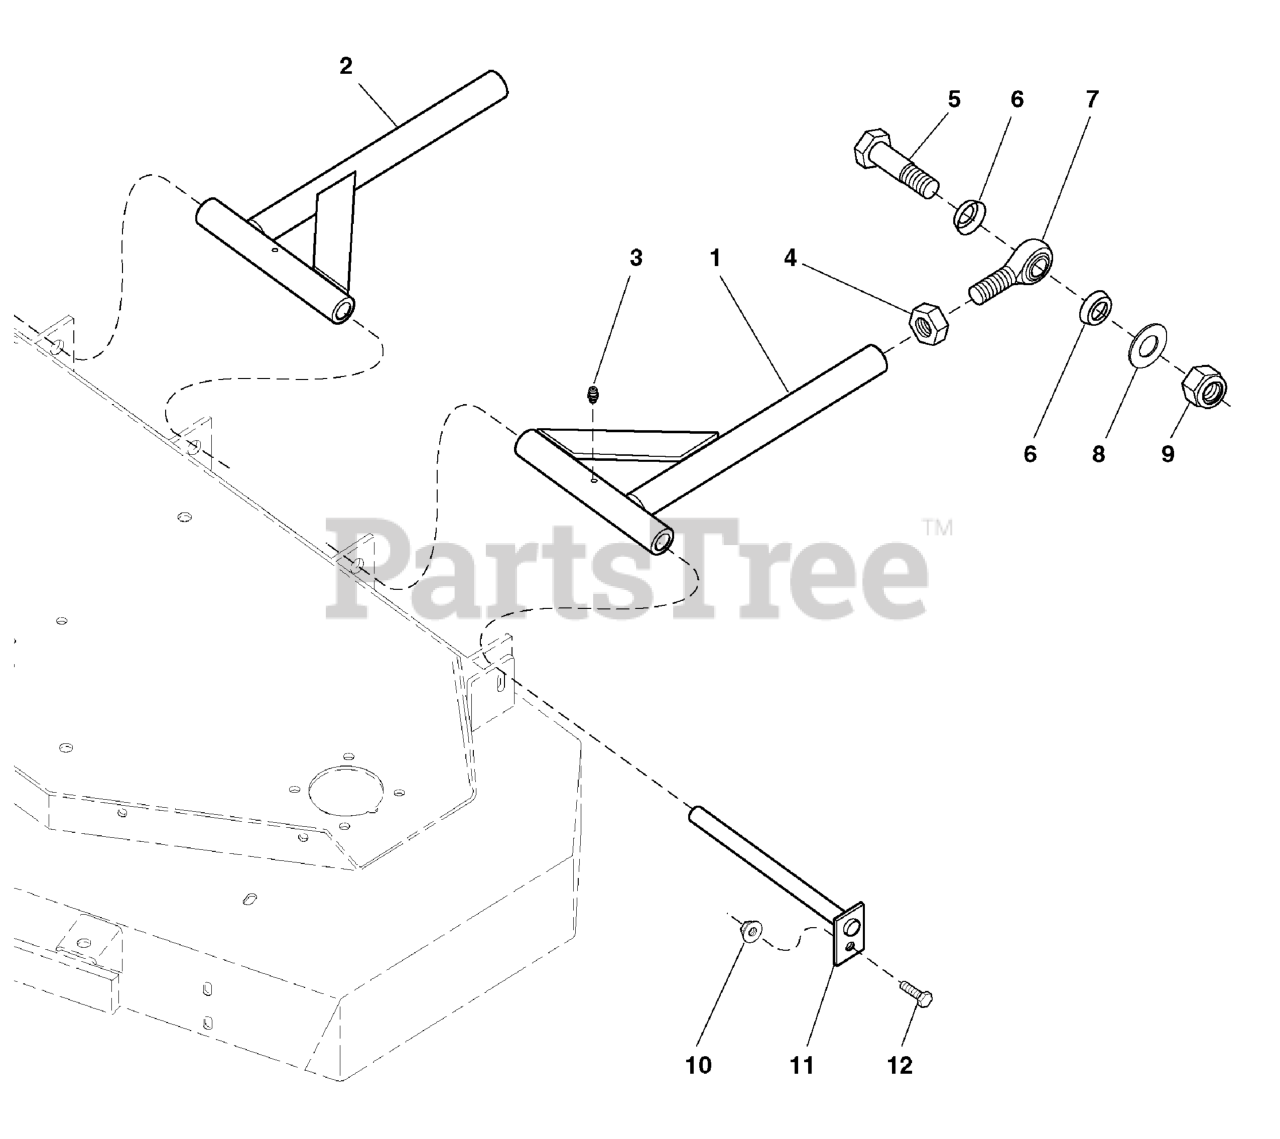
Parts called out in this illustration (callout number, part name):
1	52" DECK PUSHER BAR-LH
2	52" DECK PUSHER BAR-RH
3	GREASE FITTING
4	NUT, 3/4-16 Hex Jam
5	BOLT, 3/4-16 x 3
6	ROD END SEAL
7	BALL JOINT, 3/4-16 Male
8	WASHER, 3/4 SAE
9	NUT, 3/4-16 Hex Nylon Lock
10	NUT, 5/16-18 HEX SERRATED FLANGE (LARGE)
12	BOLT, 5/16-18 X 1 GD5 YZ
